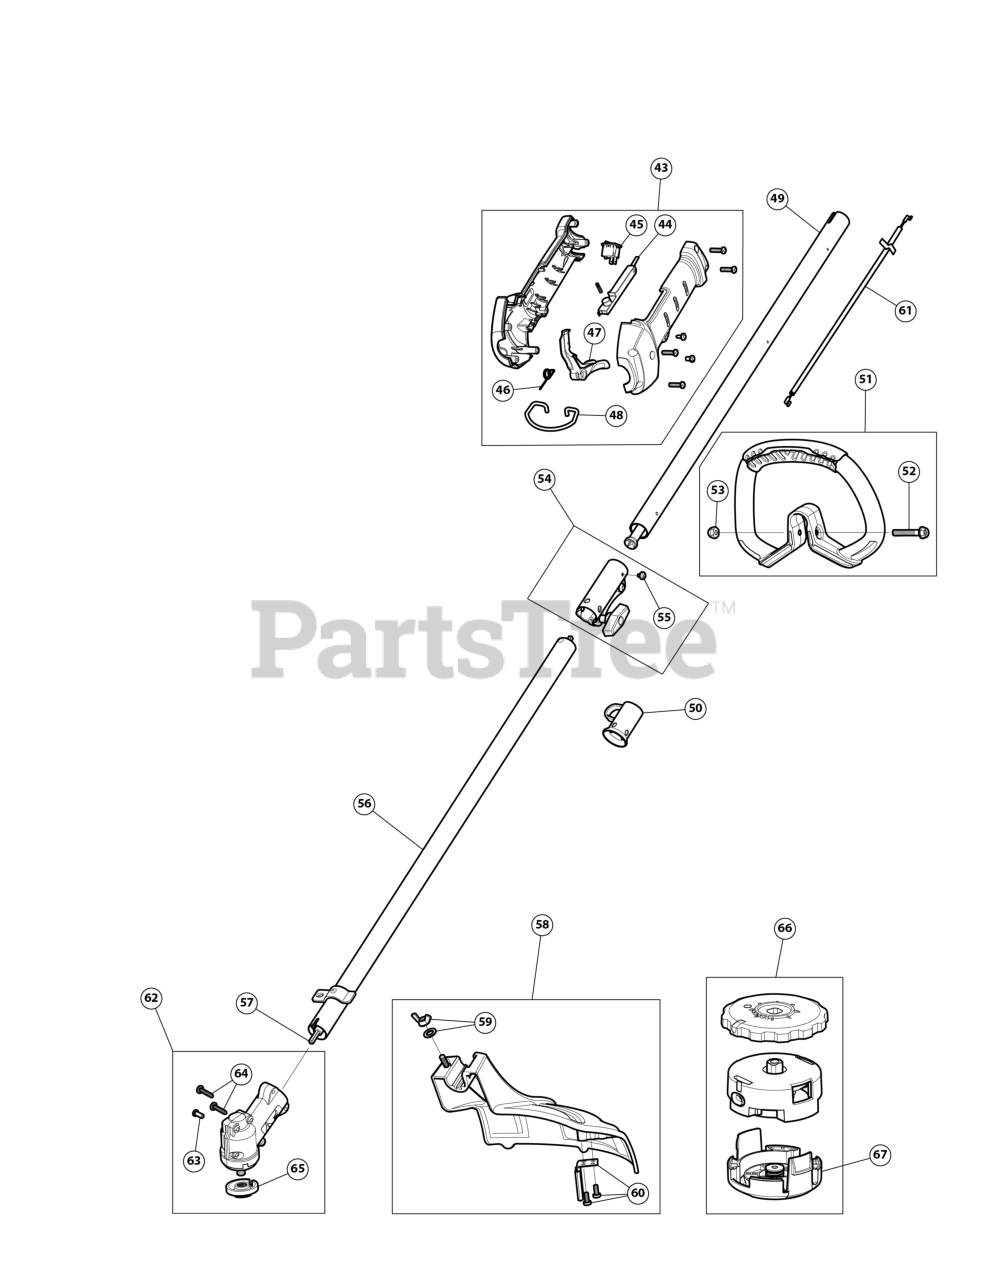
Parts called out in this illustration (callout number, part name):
43	THROTTLE GRIP ASM
44	LEVER LOCK OUT
45	SW, MOMENTARY ON/O
46	TRIGGER SPRING
47	THROTTLE TRIGGER
48	SHOULDER STRAP CLIP
49	UPPER SHAFT HOUSING
50	HANGER
51	HANDLE DLX
52	BOLT 1/4-20X1 1/2
53	NUT 1/4-20 NYLOC
54	COUPLER ASSEMBLY
55	SCREW, 10-32X.250 TA
56	LOWER SHAFT HOUSING
57	LOWER DRIVE SHAFT
58	GUARD/BLADE ASM
59	BLADE GUARD MOUNTING HARDWARE
60	BLADE ASSEMBLY W/HDW
61	THROTTLE CABLE
62	GEARBOX LCBC
63	SCREW, 8-32 x .312 P
64	SCREW #10-24X11/16 T-25
65	CUTTING HEAD SPACER
66	CUTTING HEAD
